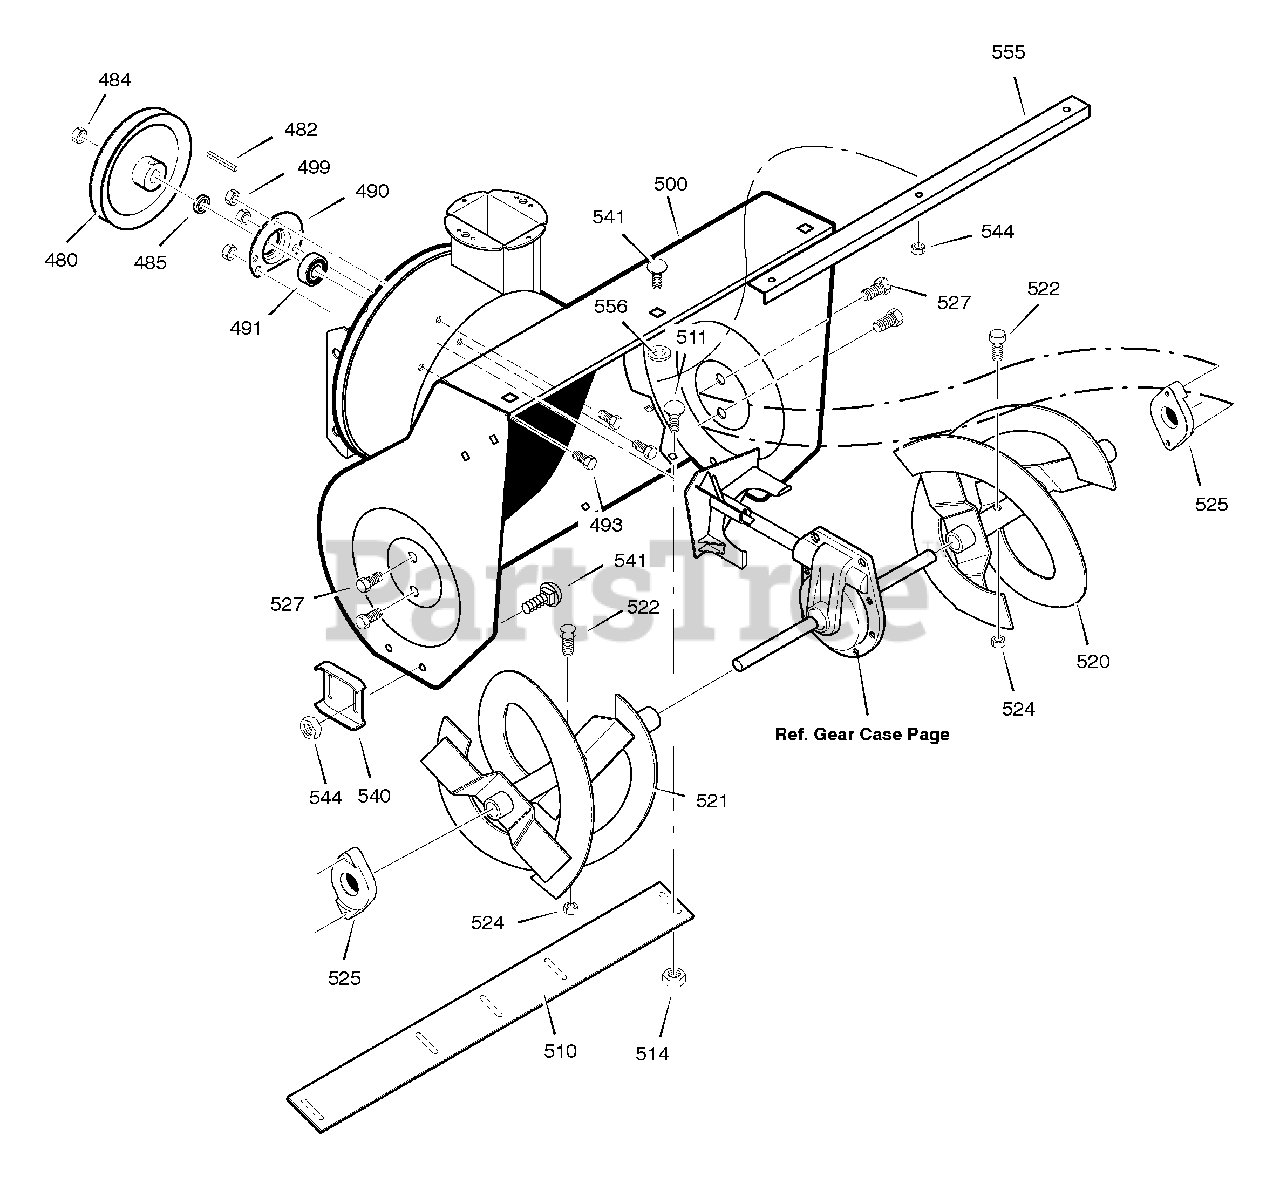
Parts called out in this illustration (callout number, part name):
480	PULLEY, 4L 8.40 OD
482	KEY, SQUARE 3/16 X 3/4
484	NUT, 1/2-20
485	SPACER, FRICTION PULLEY
490	RETAINER, BALL BRNG
491	BEARING, BALL
493	BOLT, HEX 5/16-18X .50
499	NUT, 5/16-18 HEXWDFLLK
500	HOUSING, ASSY
510	BLADE, SCRAPER
511	BOLT, 5/16-18x0.50
514	NUT, 5/16-18
520	AUGER, ASSY, LH
521	AUGER, ASSY, RH
522	SCREW, 5/16
524	NUT, 5/16
525	BEARING, FLANGE
527	SCREW, 5/16-18 x 0.75
540	SKID, HEIGHT ADJUST
541	BOLT, 5/16-18 X 0.75
544	NUT, 5/16-18
555	STIFFENER
556	WASHER
